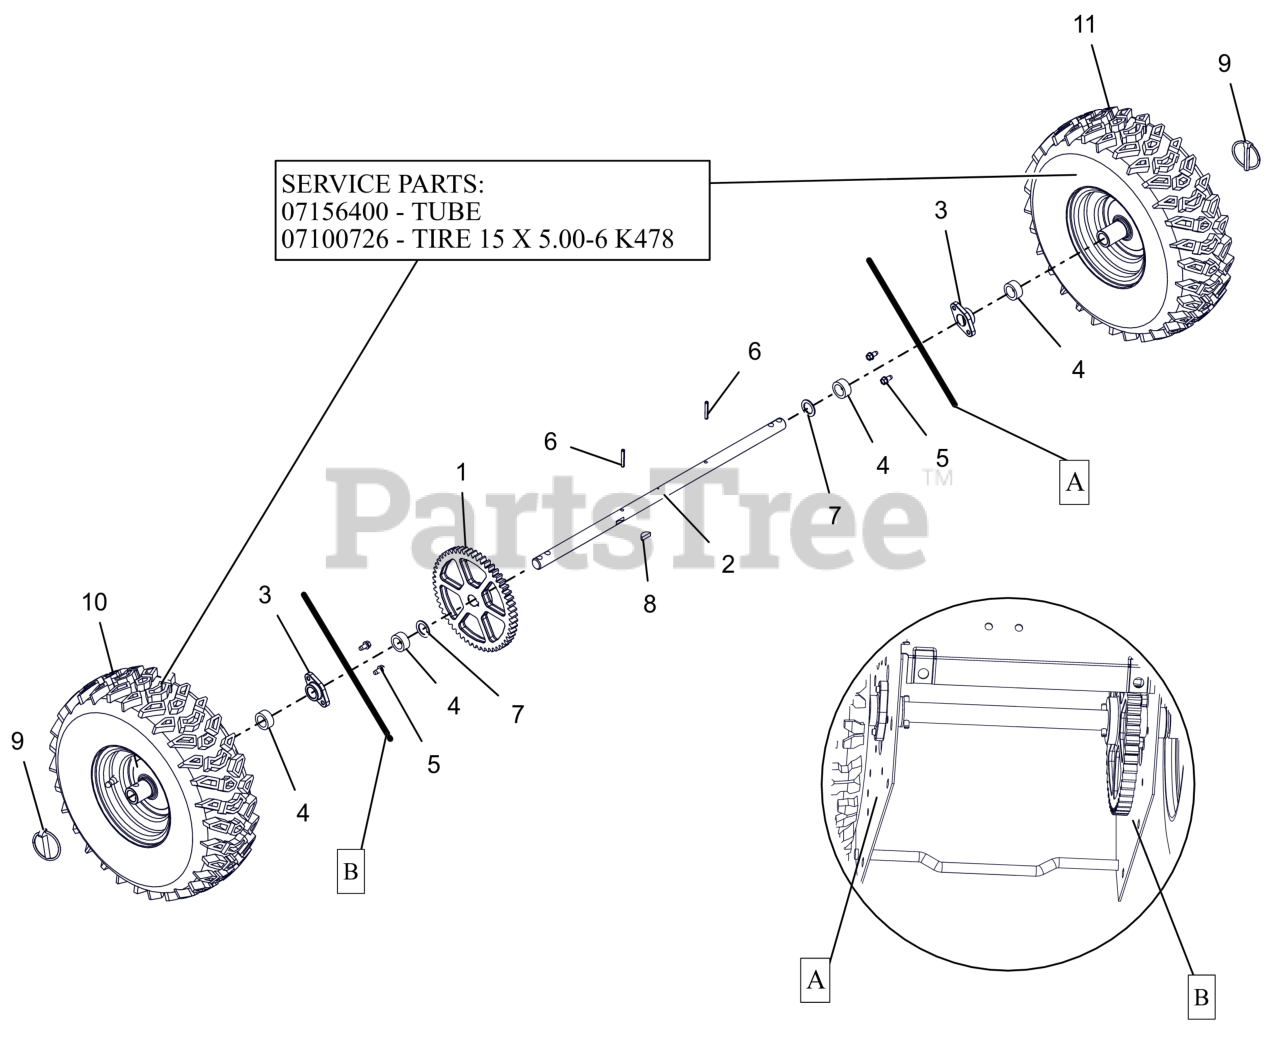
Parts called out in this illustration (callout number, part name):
1	SPUR GEAR, 54T .75ID X 6.75PD
2	AXLE, COMPACT
3	BSHG .75X1.125X.65
4	BSHG-SLV .766 X 1.125 X .500
5	SCR-TAP .25-20X.50 HWH ZCC
6	PIN-ROLL .188X1.25
7	WSHR, FLT .754X1.125X.062 ZCC
8	KEY-WDRF .25X.750X.313 SAE91
9	PIN-LOK .31X1.75
10	TIRE/WHEEL,RH 15X5.00-6 PIN T2
11	TIRE/WHEEL,LH 15X5.00-6 PIN T2
11	TUBE 15 X 5.00-6
11	TIRE, 15X5.00-6 K478
